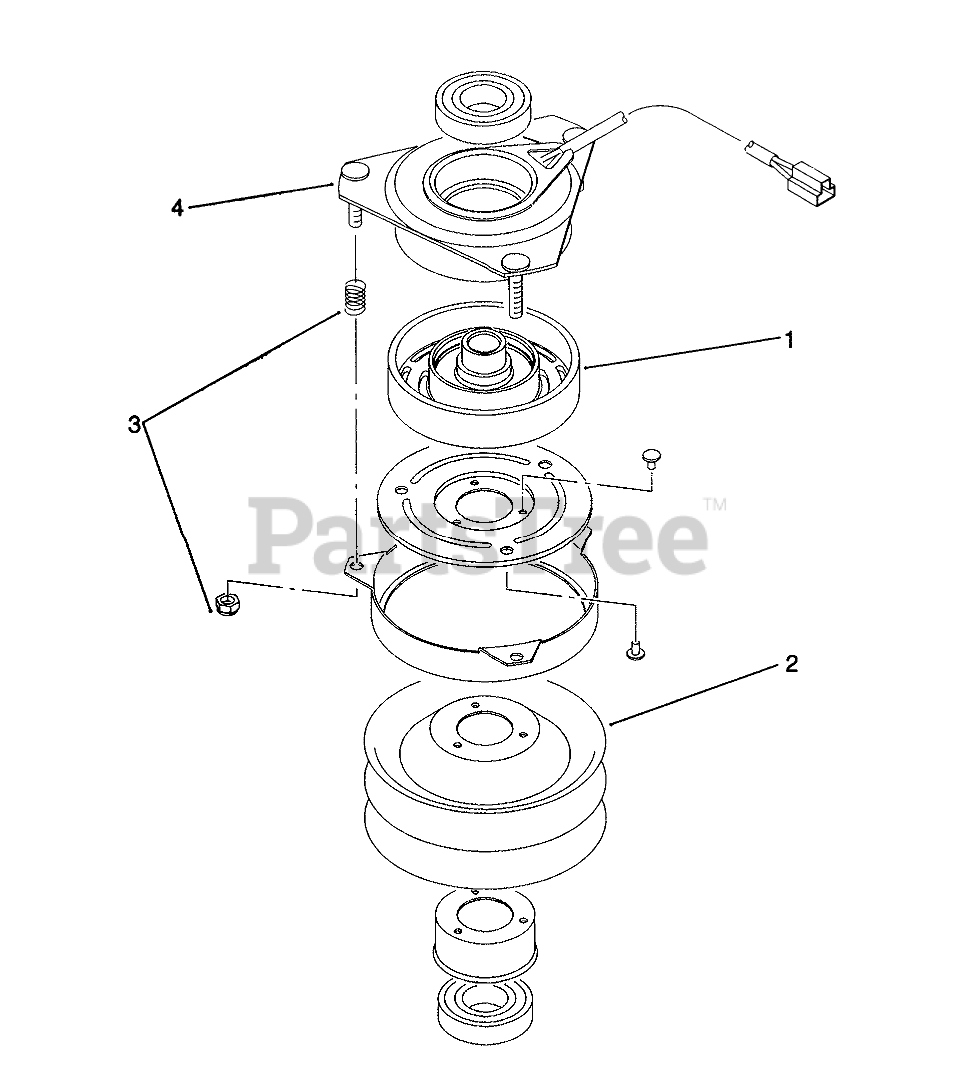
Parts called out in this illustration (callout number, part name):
1	Assembly-Rotor
2	Assembly-Armature
3	Accessories-Nuts & Springs
4	Assembly-Field
